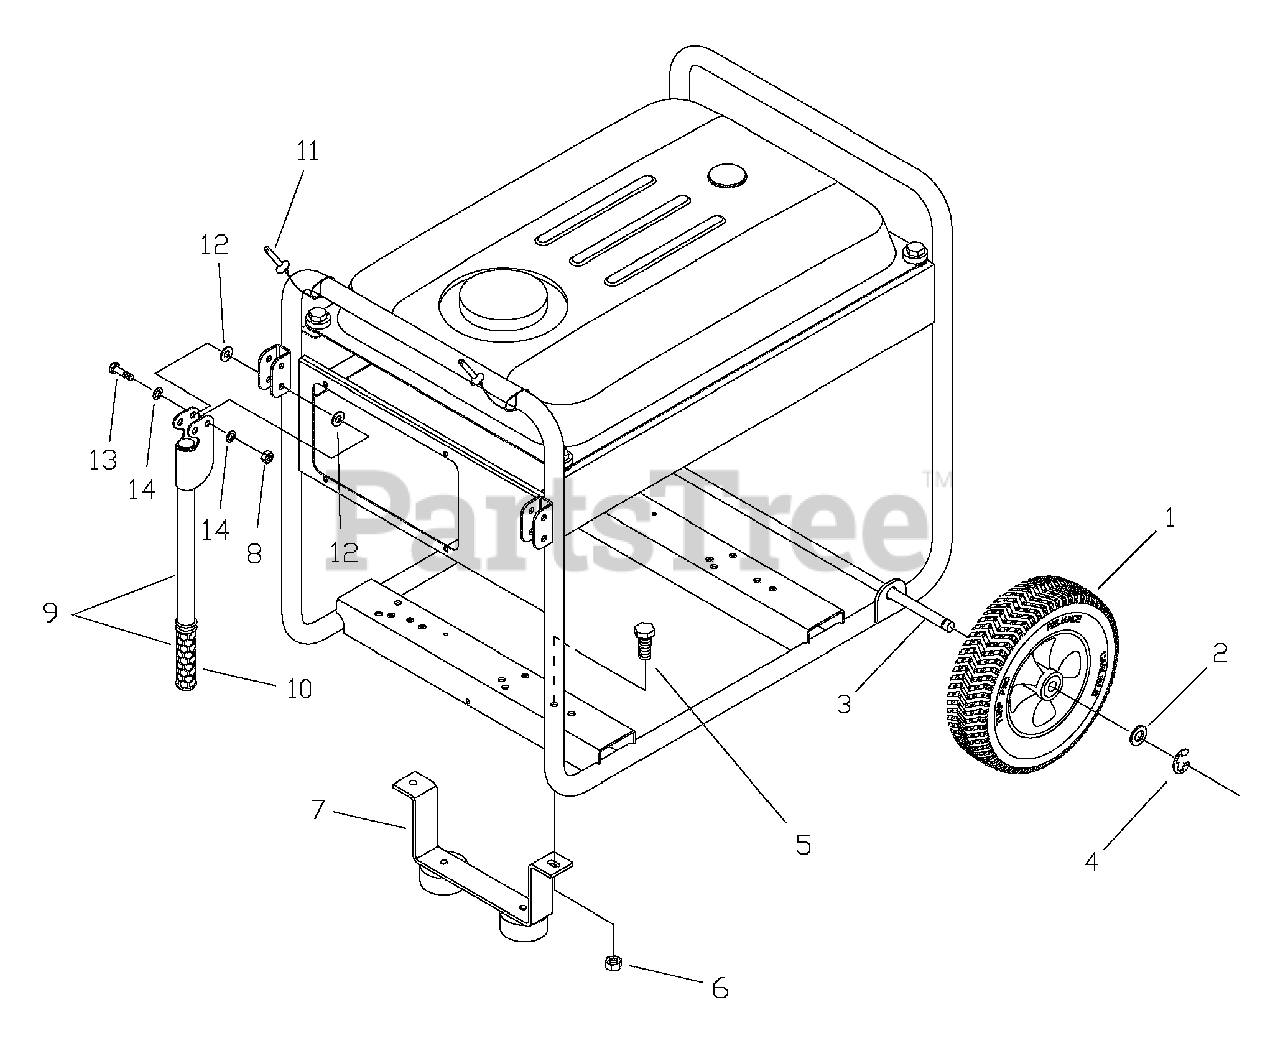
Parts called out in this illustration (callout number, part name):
2	*WASHER, 5/8
3	AXLE
4	E-RING
5	CAPSCREW, Hex Head, M8 1.25 x 20
6	NUT, Flange Serrated, M8
8	*NUT-M8 - 1.25 NYLOK
12	*WASHER, Nylon, 1.2 x 0.346 x 0.03
13	*CAPSCREW, Hex Head, M8 - 1.25 x 45
14	*WASHER, Flat, 5/16 - M8
